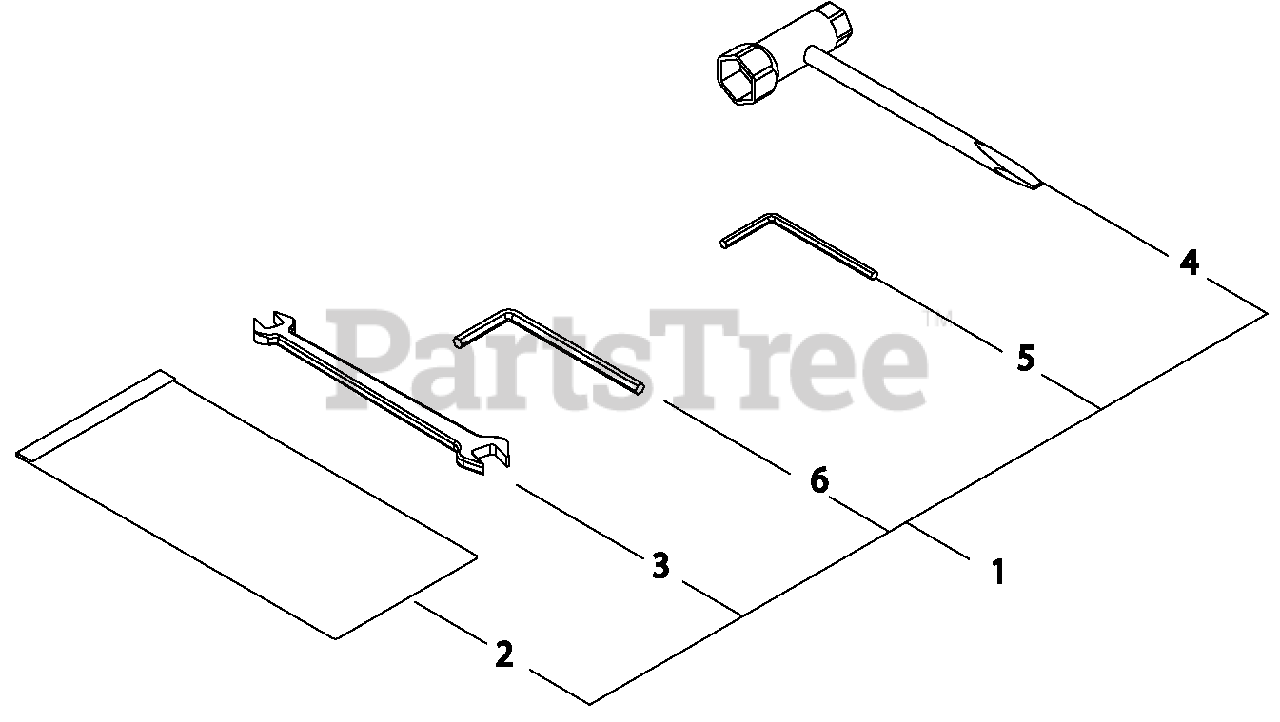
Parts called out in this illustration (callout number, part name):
1	TOOL KIT
2	BAG, TOOL
3	SPANNER - 8X10mm
4	T-WRENCH - 17X19mm
5	HEX KEY - 4mm
6	HEX KEY - 6mm
